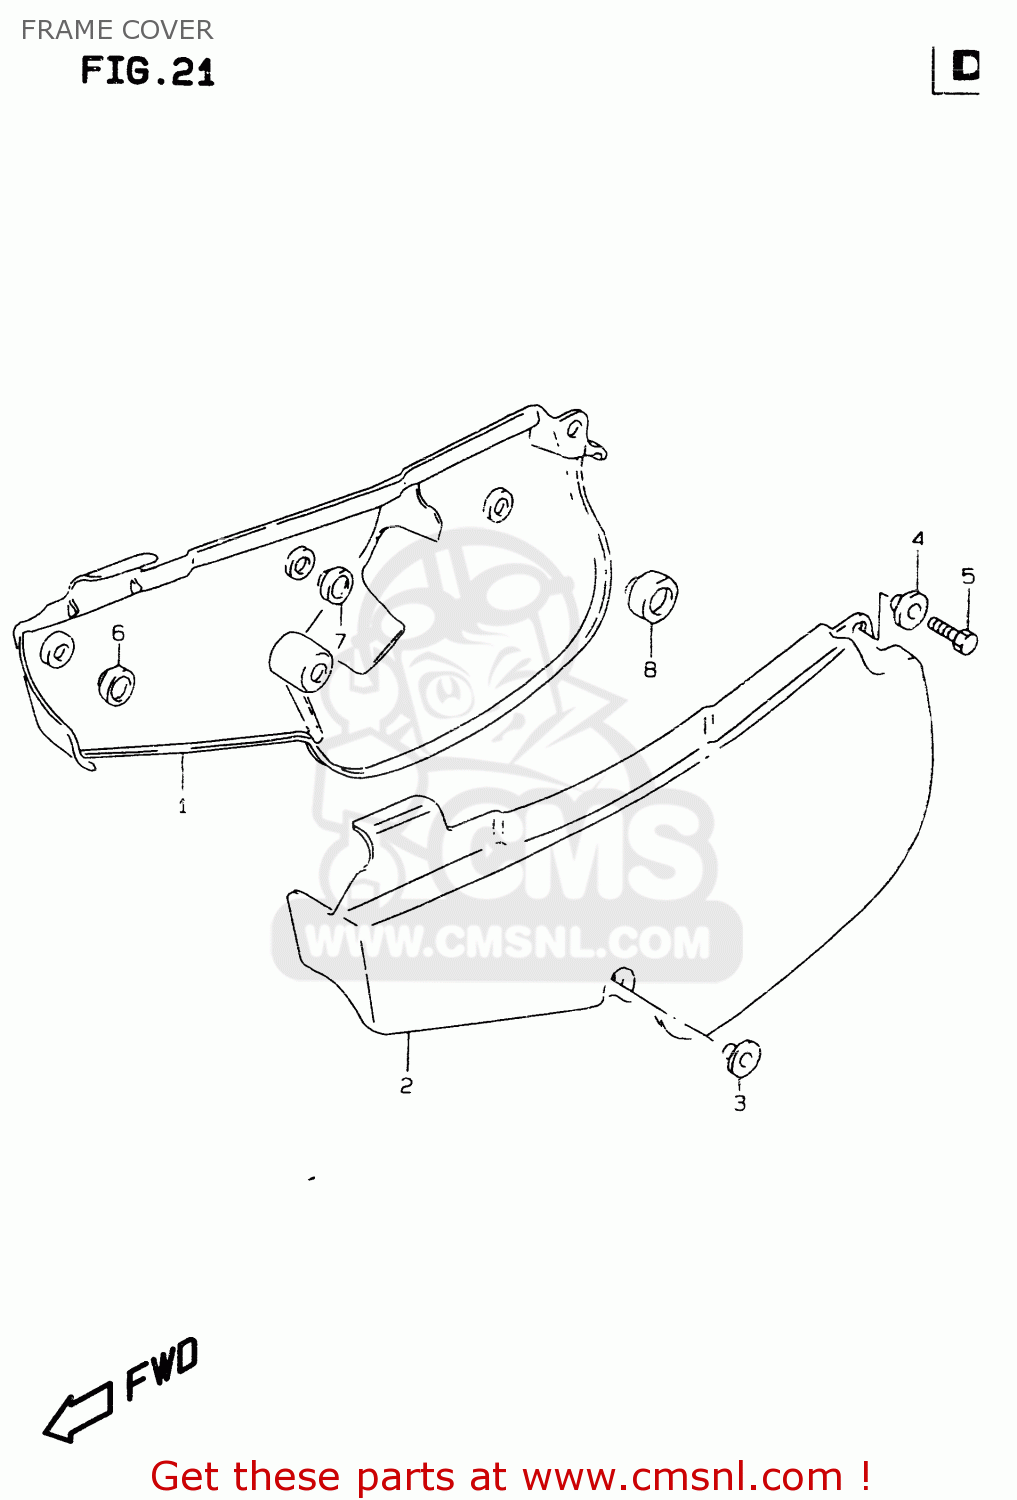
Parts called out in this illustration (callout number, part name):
1	COVER,SIDE,R(WHITE)
2	COVER,SIDE,L(WHITE)
3	WASHER
4	WASHER
5	SCREW
6	CUSHION
7	CUSHION
8	CUSHION
